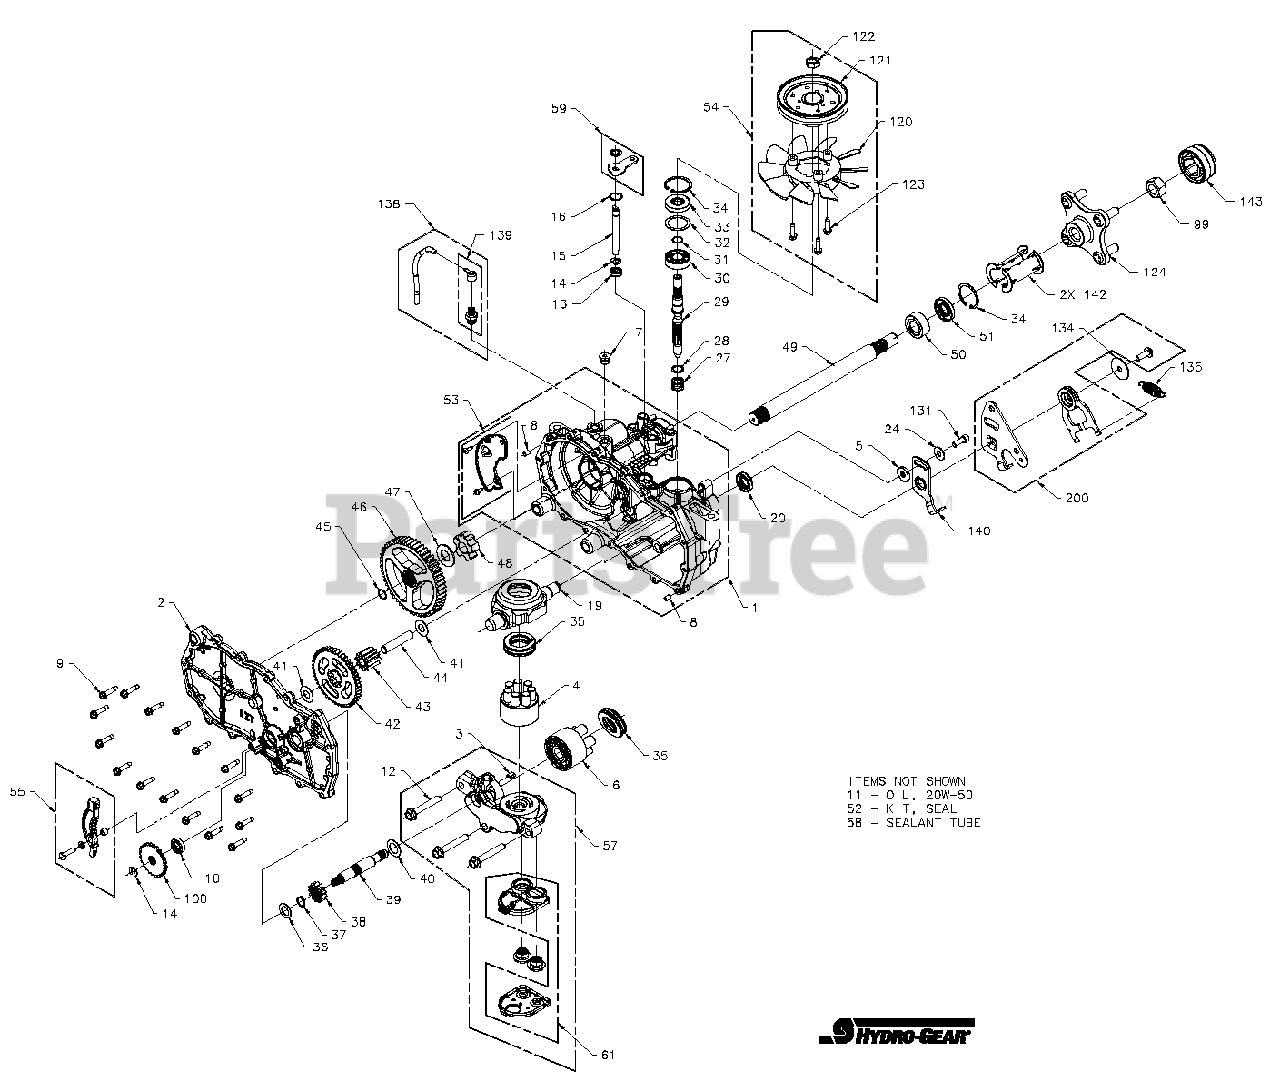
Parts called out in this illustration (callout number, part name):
1	ASSEMBLY, MAIN HOUSING - LH
4	ASSEMBLY, PUMP BLOCK (7P-10CC)
6	ASSEMBLY, MOTOR BLOCK (5P-10CC)
10	KIT, BRAKE SEAL
13	SEAL, LIP .375 X .75 X .25
14	RING, RETAINING .375 EXT
19	SWASHPLATE, TRUNNION, MACHINED
28	WASHER .591 X .787 X .040
29	SHAFT, INPUT
30	BEARING, BALL 17MM X 40MM OD X 12MM
33	SEAL, LIP 17 X 40 X 7
34	RING, RETANING
35	BEARING, THRUST 30 X 52 X 13
41	WASHER, HT .5 ID X 1.0 OD X .032
45	RING, SPIRAL RETAINING
50	BUSHING, AXLE
51	SEAL, LIP, .75 X 1.5
52	KIT SEAL
55	KIT BRAKE ARM
58	SEALANT TUBE 10.3 OZ
99	NT, HEX 3/4-16
100	DISC COG BRAKE
121	PULLEY 4/5 X 1.625
124	KIT, HUB 1/2-20
134	WASHER 1.5 X .34 X .062
135	SPRING, EXTENSION
